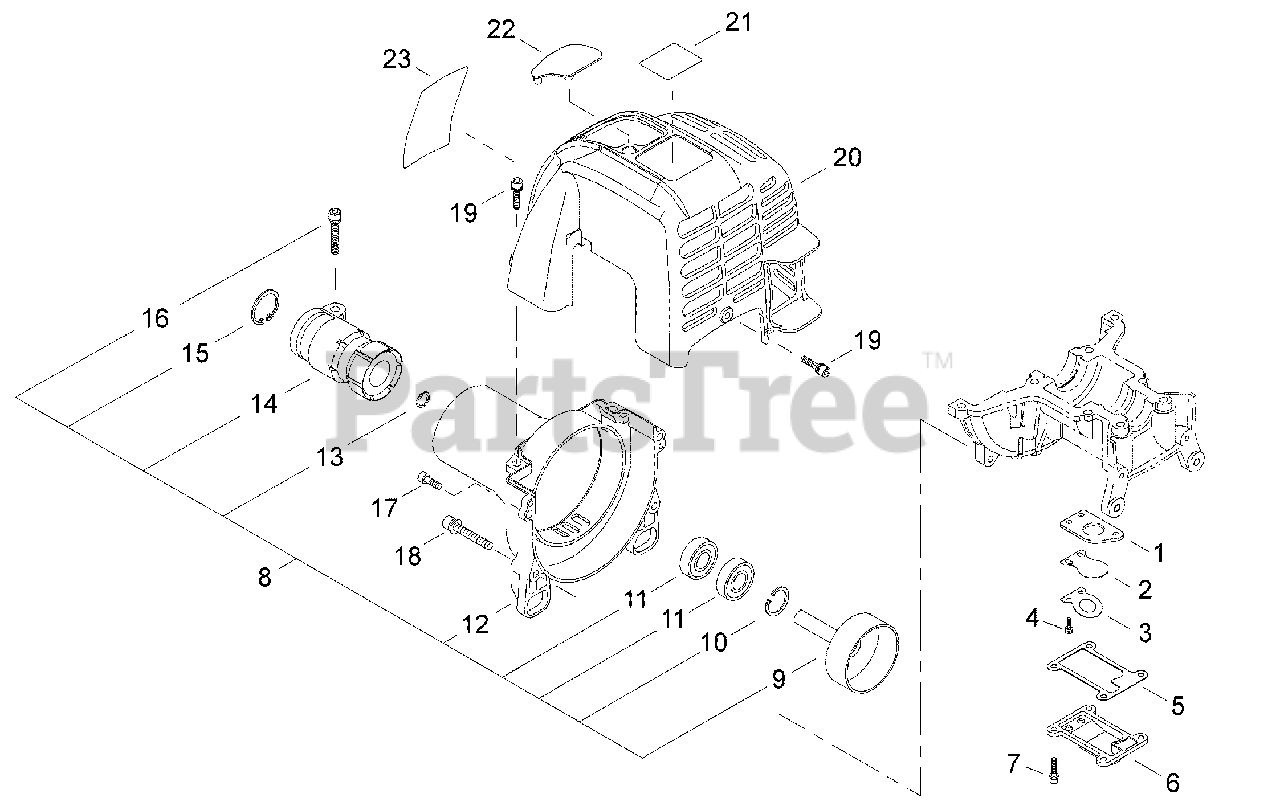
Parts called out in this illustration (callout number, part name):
1	PLATE, REED BACKING
2	VALVE, REED
3	STOP, REED VALVE
4	SCREW - 3X10
5	GASKET, REED VALVE
6	COVER, REED VALVE
7	SCREW - 4X14
8	FAN CASE ASSY
9	DRUM, CLUTCH
10	RING, RETAINING - 28
11	BEARING, BALL - 6001DDUC3
12	CASE, FAN
13	RING, RETAINING
14	CLAMP, MAIN PIPE
15	RING, RETAINING - 42
16	SCREW - 5X22
17	SCREW - 5X16
18	SCREW - 5X40
19	SCREW - 4X14
20	COVER, ENGINE
21	LABEL - MODEL B4000
22	COVER, SPARK PLUG
23	LABEL - E4
